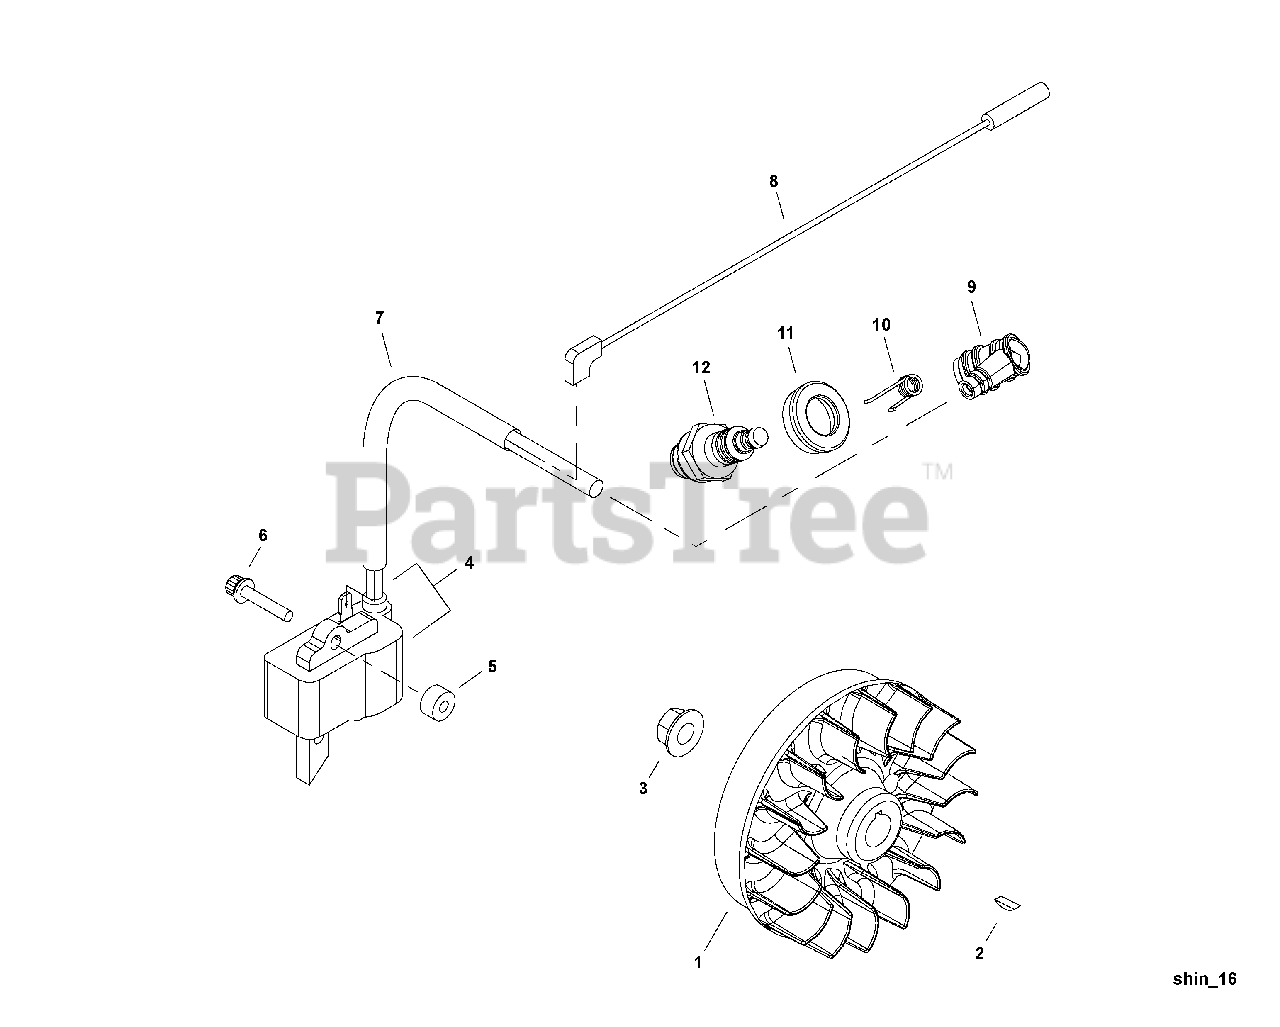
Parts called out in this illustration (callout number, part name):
1	FLYWHEEL
2	KEY - 3X10
3	NUT - 8
4	COIL, IGNITION
5	INSULATOR
6	SCREW - 4X20
7	TUBE
8	LEAD - IGNITION
9	CAP, SPARK PLUG
10	TERMINAL, SPARK PLUG CAP
11	SEAL, DUST
12	SPARK PLUG -- BPMR-6A
